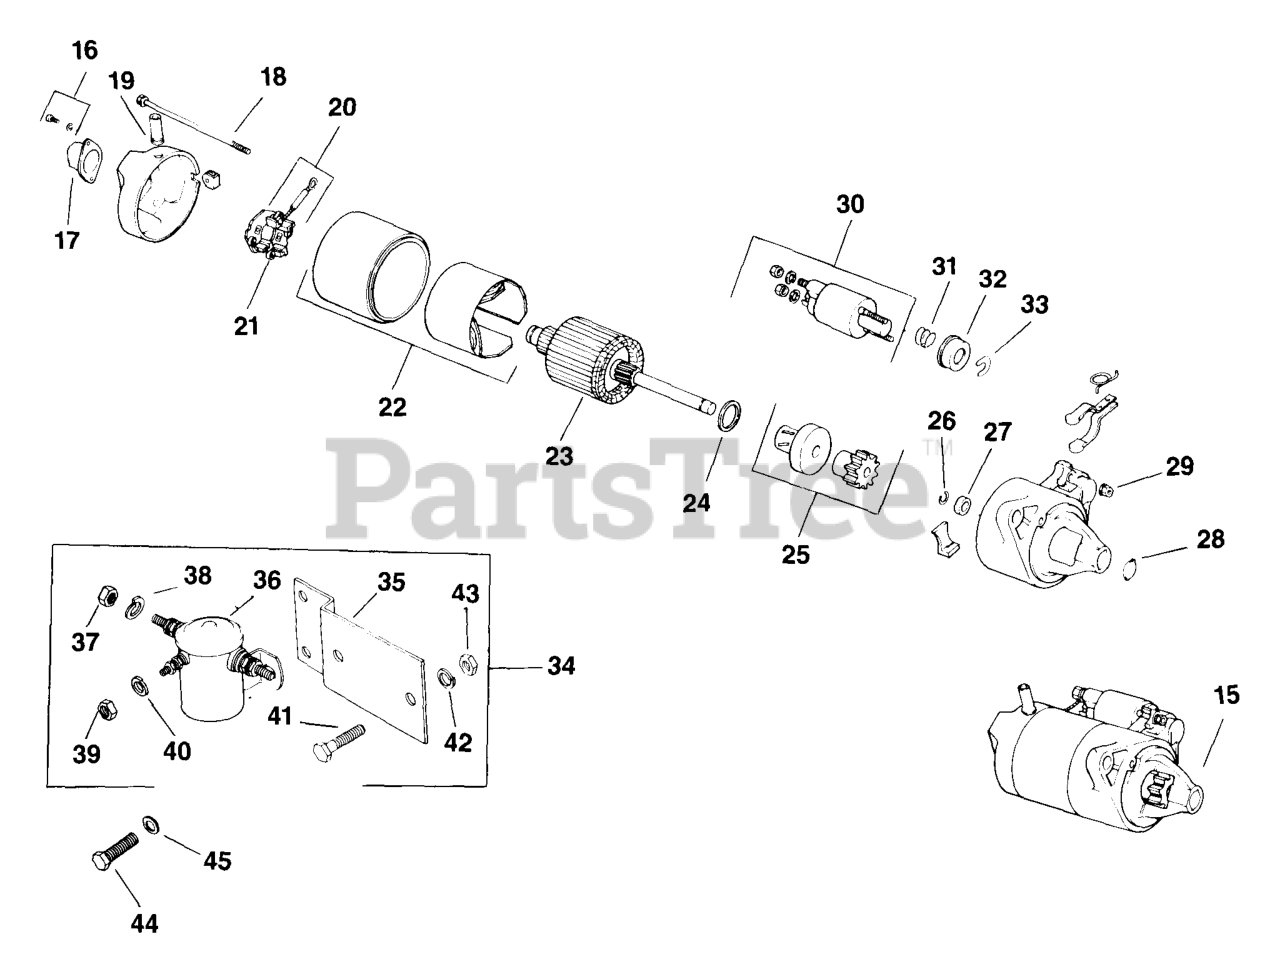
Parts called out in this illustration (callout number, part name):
34	SOLENOID/BRACKET ASSY
36	SOLENOID - DISCONTINUED
37	NUT, 5/16-18 GRADE 2 USE 25 100 21-S
38	WASHER, SPRING LOCK 5/16"
39	NUT, MACH SCREW #8-32 GRD 2 USE 25 100 16-S
40	WASHER, SPRING LOCK #8
41	SCREW, CAP HD 1/4-20X1/2"
42	WASHER, SPRING LOCK 1/4"
43	NUT, 1/4-20 GRADE 2 USE 25 100 20-S
44	SCREW, SEMS 1/4-20-1/2"
45	WASHER, FLAT 1/4" (O.D. 5/8")
